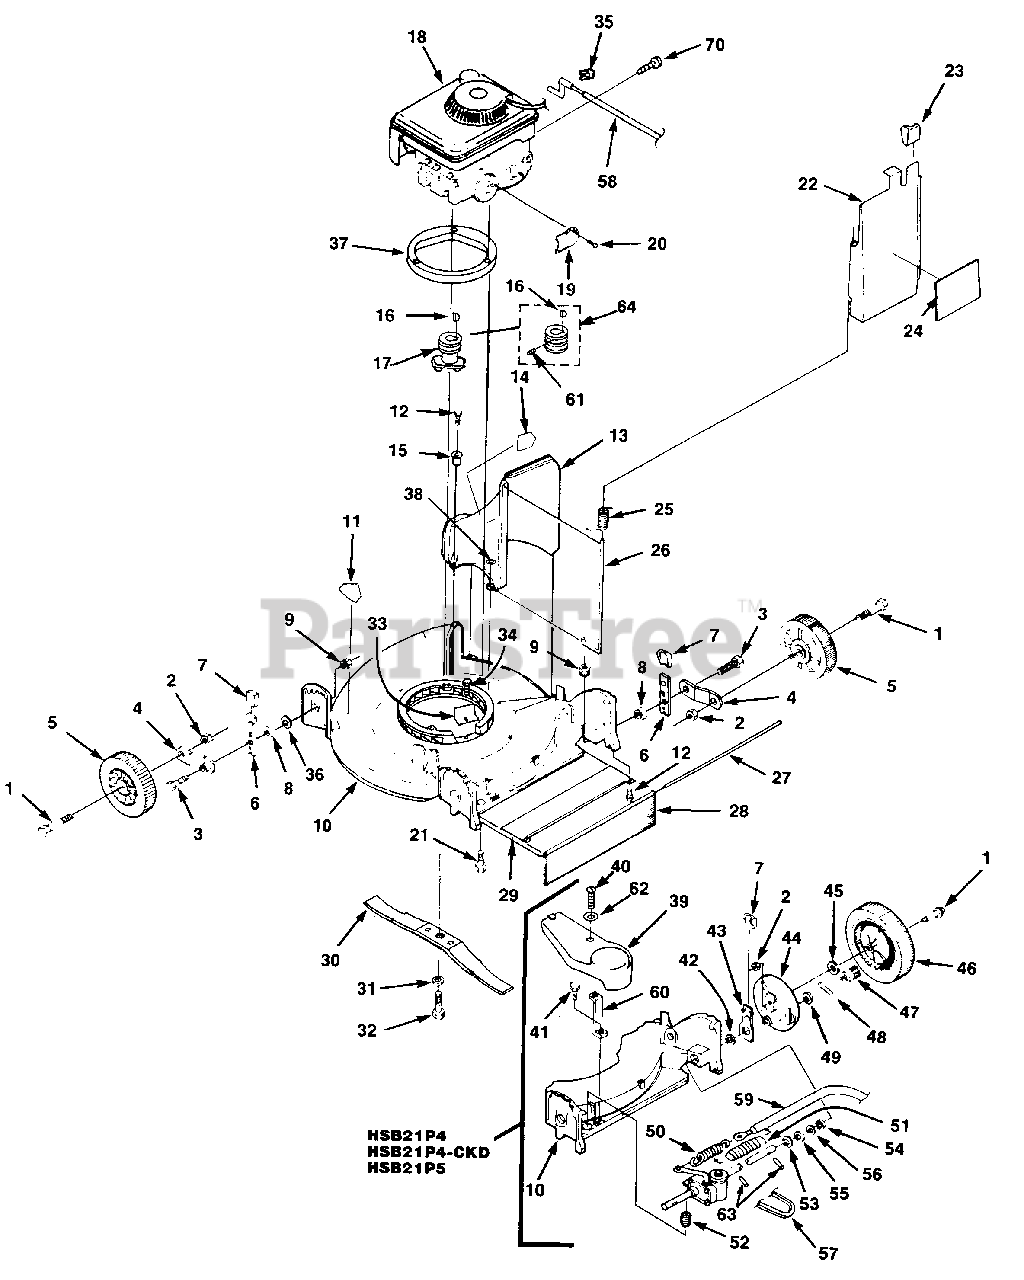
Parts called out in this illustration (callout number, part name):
1	AXLE ASSEMBLY
2	NUT
3	BOLT- Height adjusting
4	ARM- Wheel htg. adj.
5	WHEEL & TIRE
6	SPRING- Index (Front)
7	KNOB- Indexing spring
8	SPACER- Wheel height adj.
9	NUT- Flange 5/16-18
11	DECAL- Warning
12	SCREW 1/4-20 x 3/4"
13	CHUTE- Discharge
14	DECAL-CPSC
15	EYELET- Stimpson
16	KEY- Woodruff
17	ADAPTER- Blade
18	ENGINE
19	DEFLECTOR
20	SCREW- #8-32 x 3/8"
21	SCREW- 3/8-16 x 2 1/4"
22	DOOR- Chute
23	KNOB- Index spring
24	DECAL- Door (warning)
25	SPRING- Chute door
26	PIN- Hinge
27	ROD- Drag flap
28	FLAP- Drag
29	COVER- Rear
30	BAR- Cutter
31	WASHER- Lock 3/8"
32	SCREW- Hex hd. 3/8-24 x 1 1/4"
33	COVER- Belt opening
34	SCREW- 1/4-20 x 1/2"
35	STOP- Rope
36	WASHER- Flat (5/16")
37	RING- Engine
38	WASHER- Plain (1/4")
39	COVER- Drive
40	SCREW- 1/4-20 x 3/4"
41	SCREW- Hex #10-16
42	SPACER- Rear hgt. adj.
43	SPRING- Index
44	SUPPORT- Drive wheel
46	WHEEL & TIRE
47	PINION (L.H.)
48	PIN- Drive
50	SPRING- Extension
51	COVER- Spring
52	SPRING- Compression
53	RING- Eaton
57	BELT- Drive
58	CONTROL- Engine
59	CABLE- Traction control
60	SUPPORT- Belt cover
61	SCREW- 1/4-20 x 3/8"
62	WASHER- Plain
63	PIN- Roll 1/8 x 7/8
64	PULLEY- Drive
